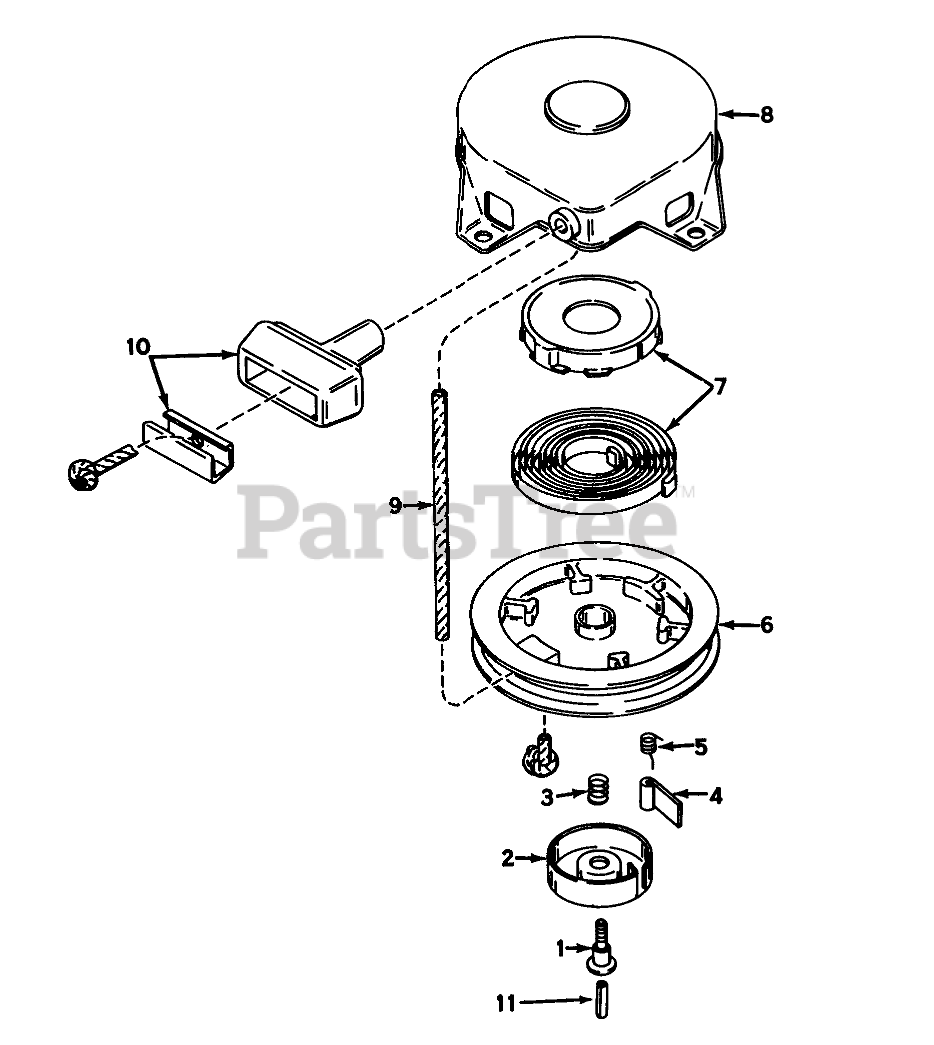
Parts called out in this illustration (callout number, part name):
2	Retainer
3	Spring-Brake
4	Dog-Starter
5	Spring-Dog
7	Spring & Keeper Assy
8	Housing Assy., Starter (Incl. Ref. #1)
9	Rope-Starter
10	Assy., Starter
11	Centering
